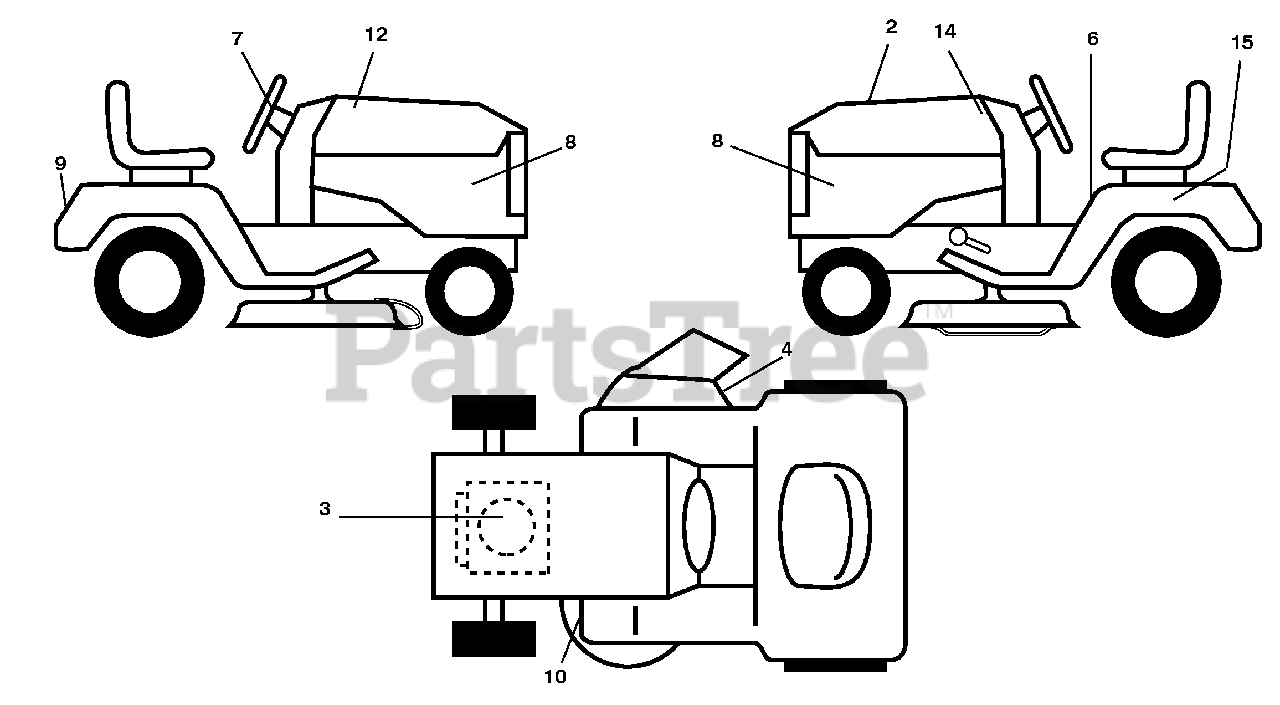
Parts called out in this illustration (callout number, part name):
2	Decal, Replacement
3	Decal, Engine HP
4	Decal, Warning
6	Decal, Fender Warning (E&F)
7	Decal, Ins Str Wh
8	Decal, Side Panel
9	Decal, Fender
10	Decal, V-Belt Sch.
12	Decal, Hood RH
14	Decal, Hood LH
15	Decal, Caution, Battery
15	Decal, Handle Lft Height Adj.
15	Manual, Operator's, English & French
15	Manual, Parts, English & French
